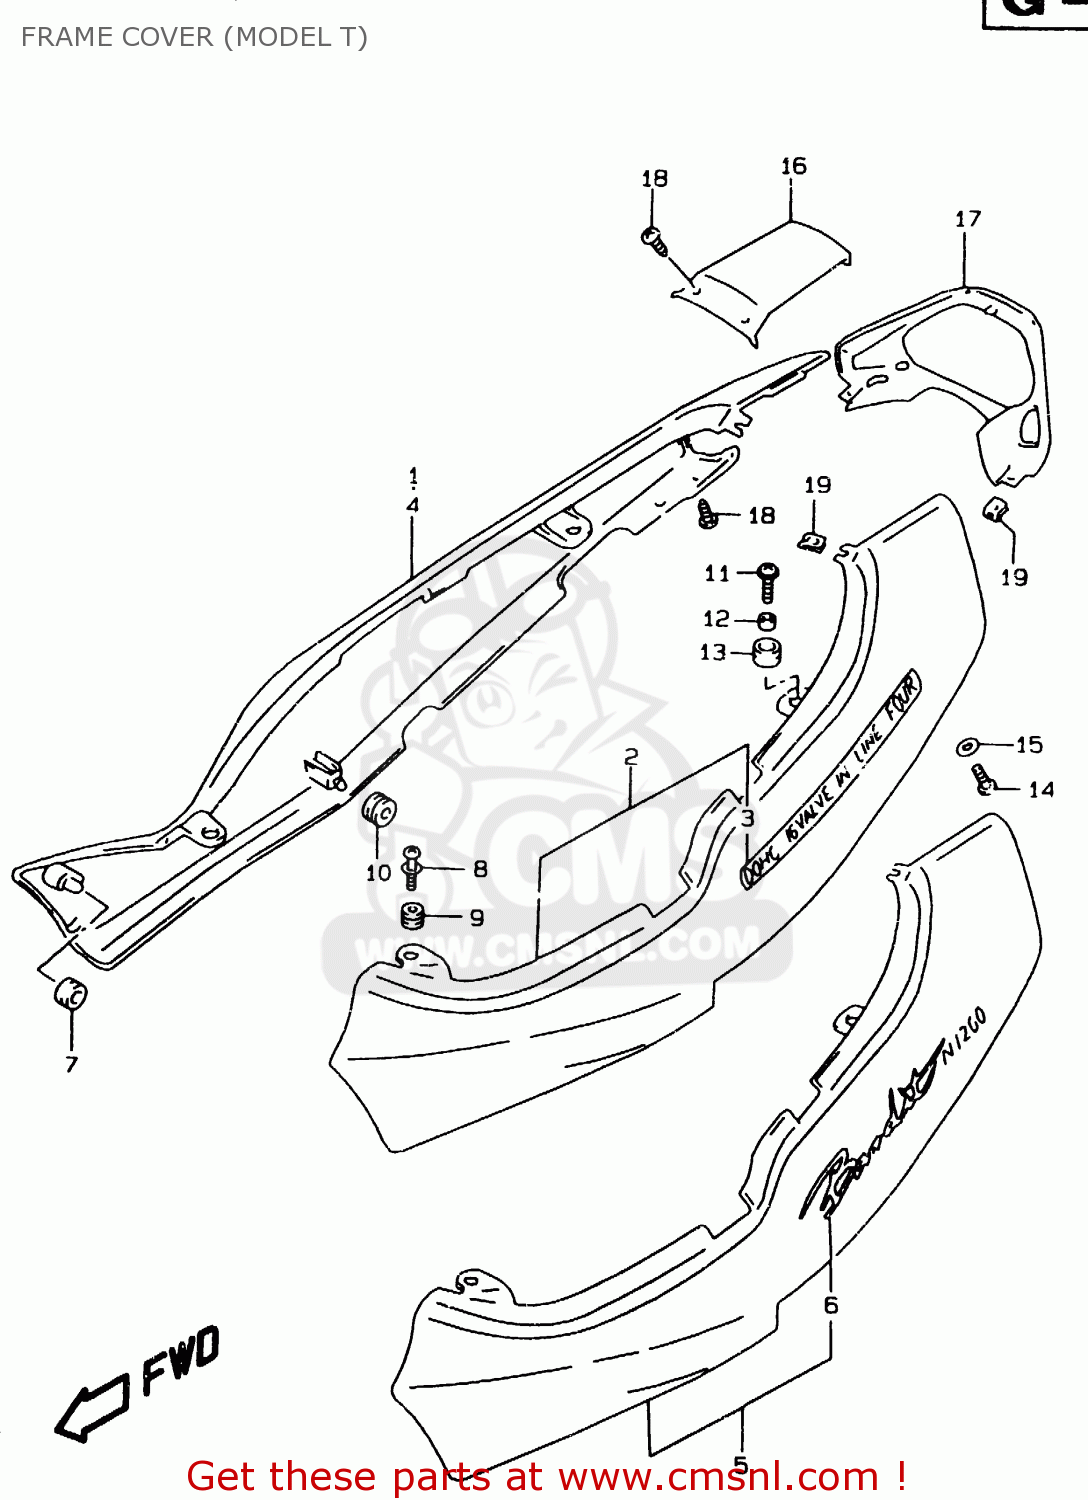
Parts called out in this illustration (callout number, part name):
1	COVER,FRAME,R
2	COVER,FRAME,L.
3	EMBLEM,FRAME COVER
4	COVER,FRAME,R.
5	COVER,FRAME,L(BLACK)
6	EMBLEM,FRAME COVER
7	CUSHION,FRAME COVER FR
8	CLIP
9	CUSHION
10	CUSHION
11	SCREW(6X20)
12	SPACER (6,8X10X9.4)
13	CUSHION
14	SCREW
15	WASHER(6.3X16X1.5)
16	COVER,FRAME CTR
17	COVER,FRAME RR
18	SCREW
19	NUT
